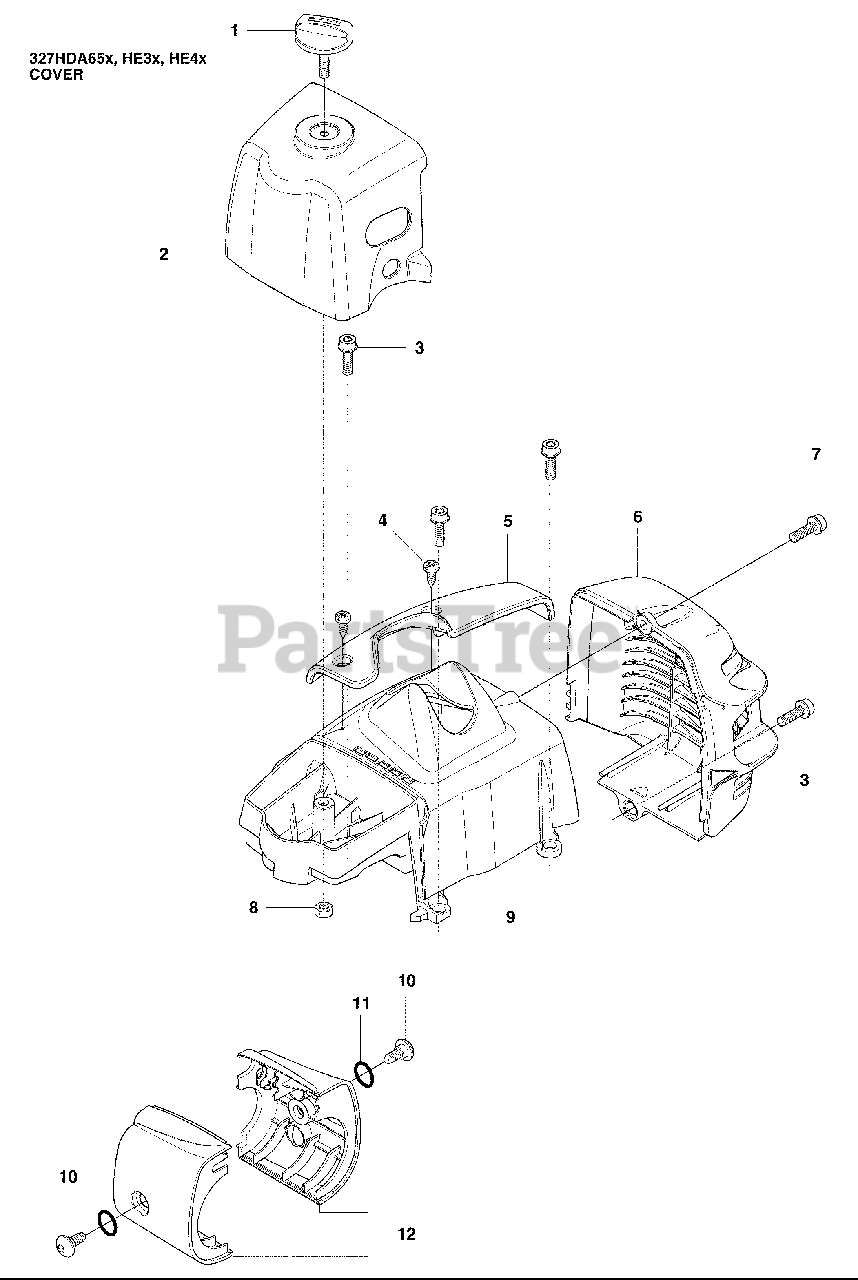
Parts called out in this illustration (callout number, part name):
2	Air Filter Cover
3	Screw, Ihscfm
5	ARM PROTECTION
6	RP HEAT PROTECTOR
9	RP CYLINDER COVER
10	Screw, Mt5 X 11
11	O-Ring, 8 X 1.6
